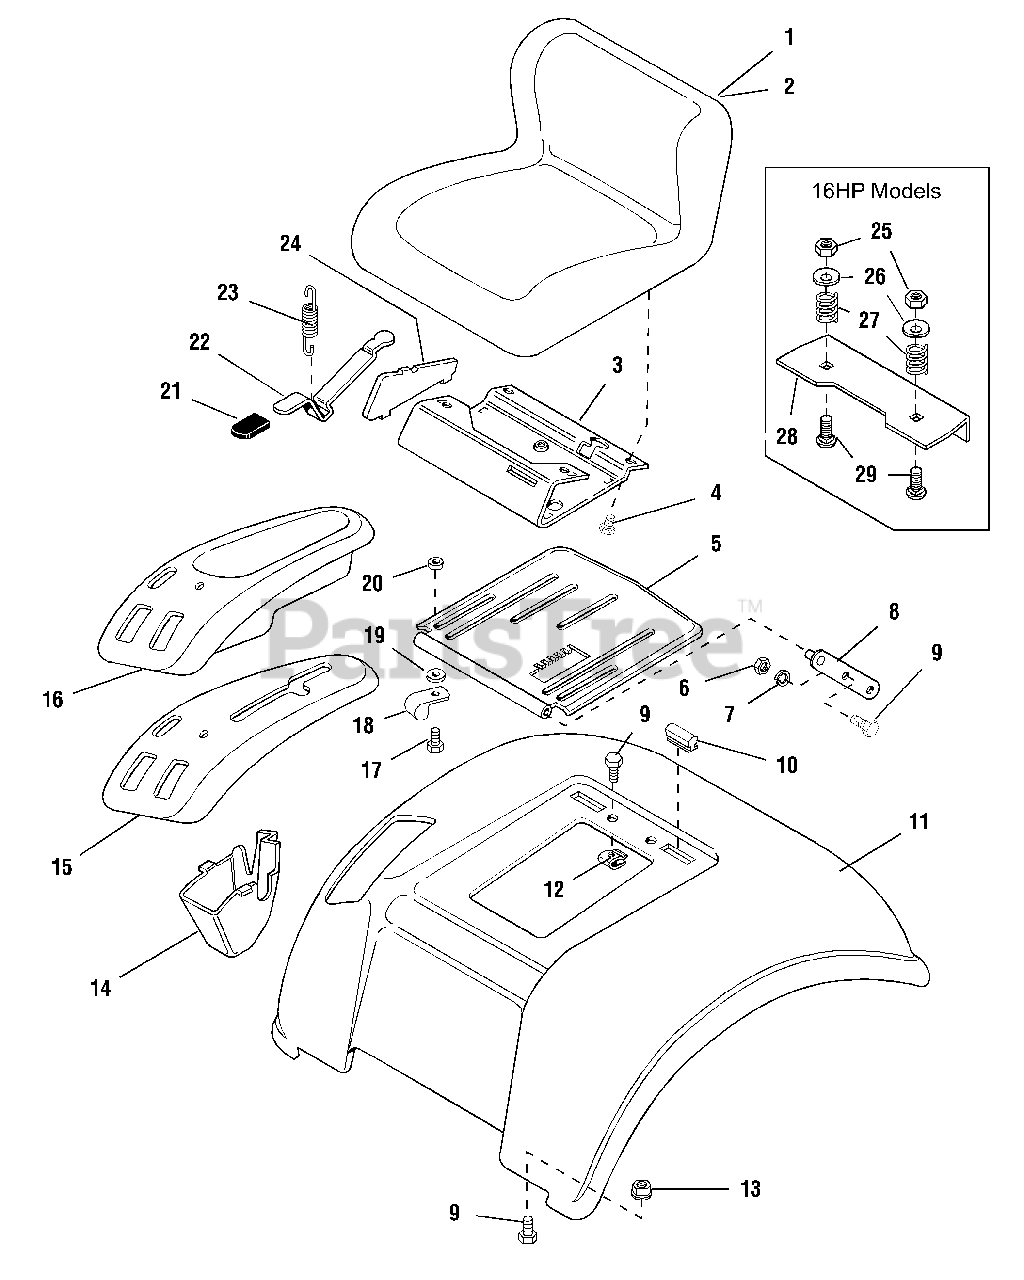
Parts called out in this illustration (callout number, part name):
1	SEAT ASSY.
2	COVER, Seat
3	SLIDE, Seat
4	SCREW, Hex, Whiz, 5/16-18 x 1/2
6	NUT, Hex, Full, 5/16-18
7	LOCKWASHER, 5/16
8	BAR ASSY., Seat Pivot
9	SCREW, Whiz, 5/16-18 x 3/4
10	STOP, Seat, Rubber
11	SEAT DECK, Orange
11	SEAT DECK, Red
13	NUT, Hex, Lock, 5/16-18
14	GUARD, Splash, Pod
15	CONTROL POD, Gear
16	CONTROL POD, Hydro
17	SCREW, Taptite, 5/16-18 x 5/8
18	CLAMP, Wire
19	WASHER, 5/16
22	LEVER, Seat Latch
23	SPRING, Extension
24	SIDE PANEL, Seat Slide
25	NUT, Nylock, 5/16-18
26	WASHER
27	SPRING, Seat
28	PLATE, Spring Support
29	CARRIAGE BOLT, 5/16-18 x 1.0
